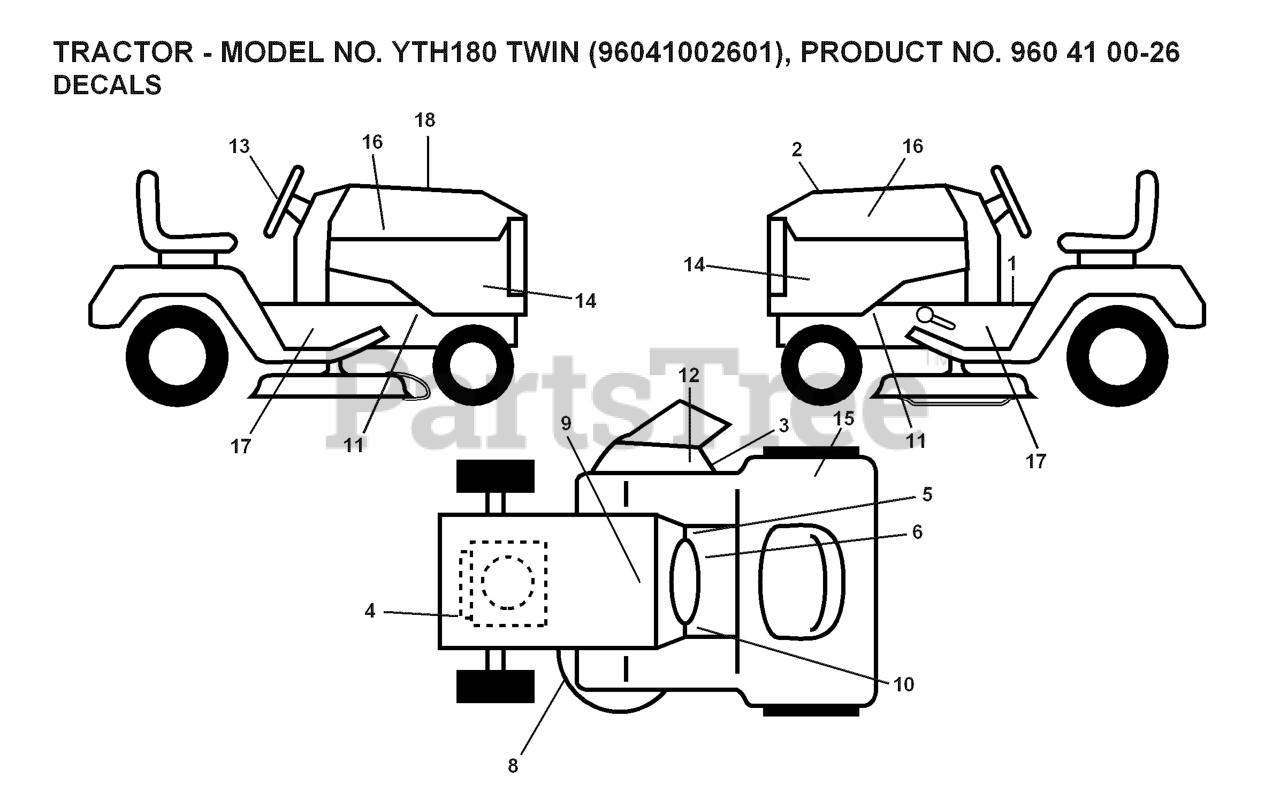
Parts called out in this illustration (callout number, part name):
1	LABEL
2	DECAL.HOOD.TOP.INSERT.
3	DECAL, DEFLECT WARNING
4	DECAL
5	DECAL PARK BRAKE
6	DECAL
8	DECAL V BELT SCHEMATIC
9	DECAL BTRY SYMBOLS
10	DECAL
12	DECAL.INTERNATIONL.CUTFINGER
13	DECAL.WHEEL.STRG.LGN.H
15	Decal, Fender 100 DB/CE
16	DECAL.HOOD.NAMELOGO.HUSQ
